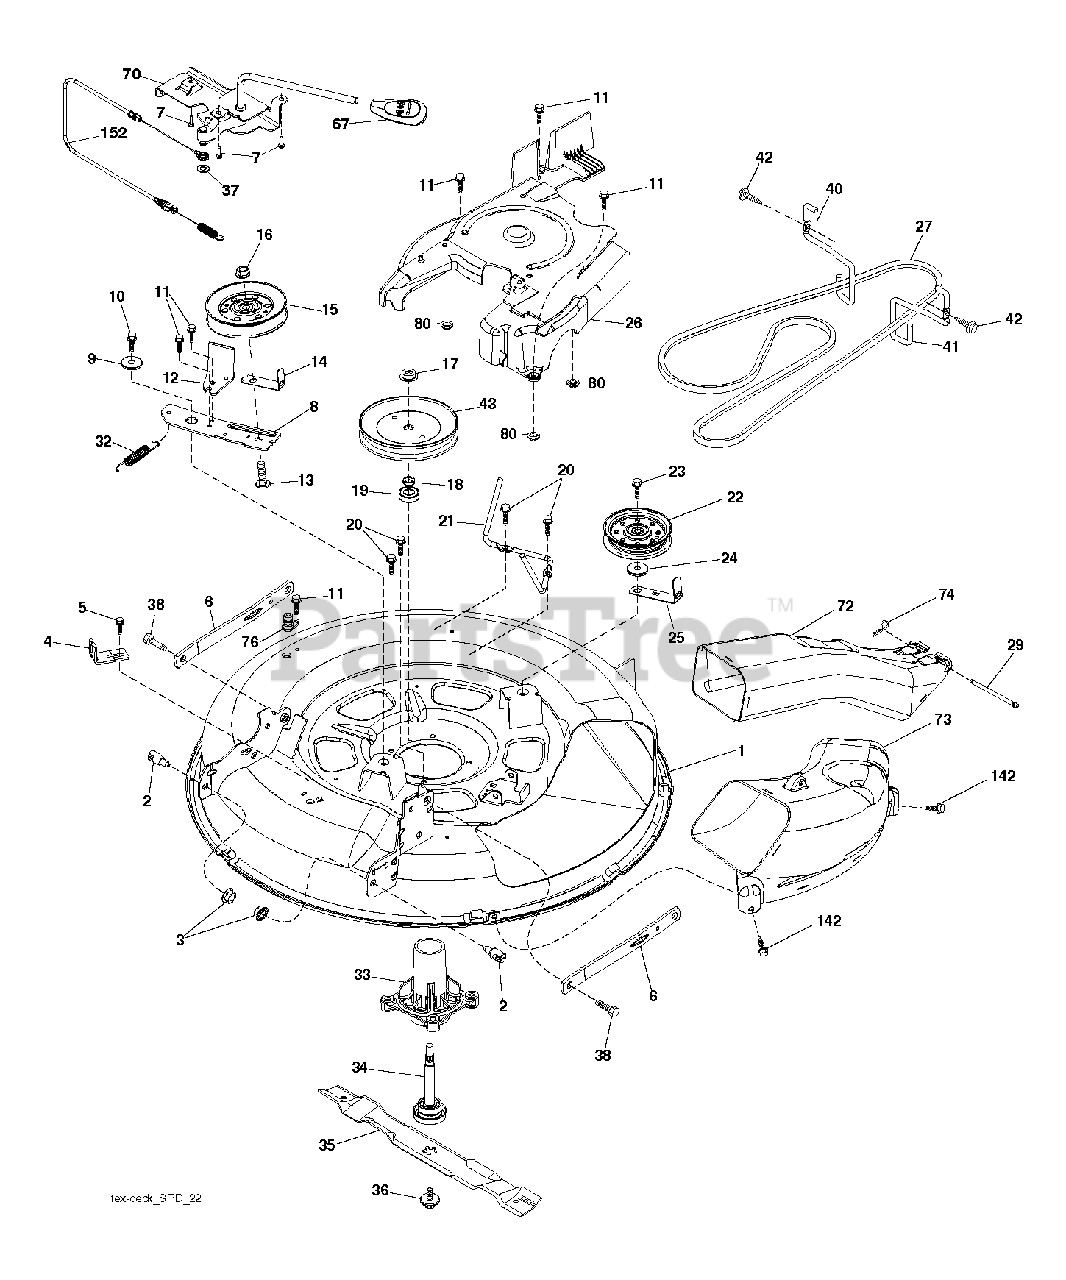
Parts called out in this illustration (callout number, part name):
1	DECK.WELDMENT.30"SRD.BLACK
2	STUD.FASTNER.W/ANTI-ROTATE
3	NUT LOCK HEX FLANGE 5/16-18
4	Clutch Cable Bracket
5	BOLT.5/16HEX.WHS.HD
6	ARMS.SUSP.MOWER.REAR.SRD
7	SCREW.#10 X 0.750.BOS THREAD
8	ARM.IDLER.30"SRD
9	SPACER.RETAINER
10	SCREW 3/8-16X1
11	SCREW.1/4-20X5/8
12	ARM BRAKE MOWER RH
13	BOLT.3/8-16X1.50
14	KEEPER, BELT IDLER
15	PULLEY.IDLER.4.25
16	NUT LOCK FLG 3/8-16 UNC
17	NUT.FLANGE.LOCK.TOP
18	WASHER.SPACER.MANDREL
20	SCREW, WASHER HEAD
21	KEEPER.BELT.MANDREL.30"
22	PULLEY.IDLER.FLAT.UNPLATED
23	SCREW LT
25	KEEPER.BELT.30"SRD
26	Mandrel Cover, 30" Deck
27	V-BELT.DRIVE.MOWER.30"
29	PIN.HINGE.30".SRD
32	SPRING RETURN
33	HOUSING MANDREL
34	SHAFT.ASM.MDRL.N/GREASE.38
35	BLADE.MOWER.BAGGING.30"
36	BOLT.WASHER.ASM.7/16-2
38	BOLT.SHOULDER
40	KEEPER.BELT.ENGINE.LH.LT.SRD
41	KEEPER.BELT.ENGINE.RH.LT.SRD
42	SCREW, 3/8-16X3/4
43	PULLEY, MANDREL 6.5 PD
70	CLUTCH.ASM.MANUAL.LT.PRED
72	CHUTE.UPPER.SRD.30R
73	Lower Chute, SRD 30R"
74	RETAINER-SPRNG RB
142	SCREW, 3/8-16X3/4
152	CABLE.CLUTCH.MANUAL.
